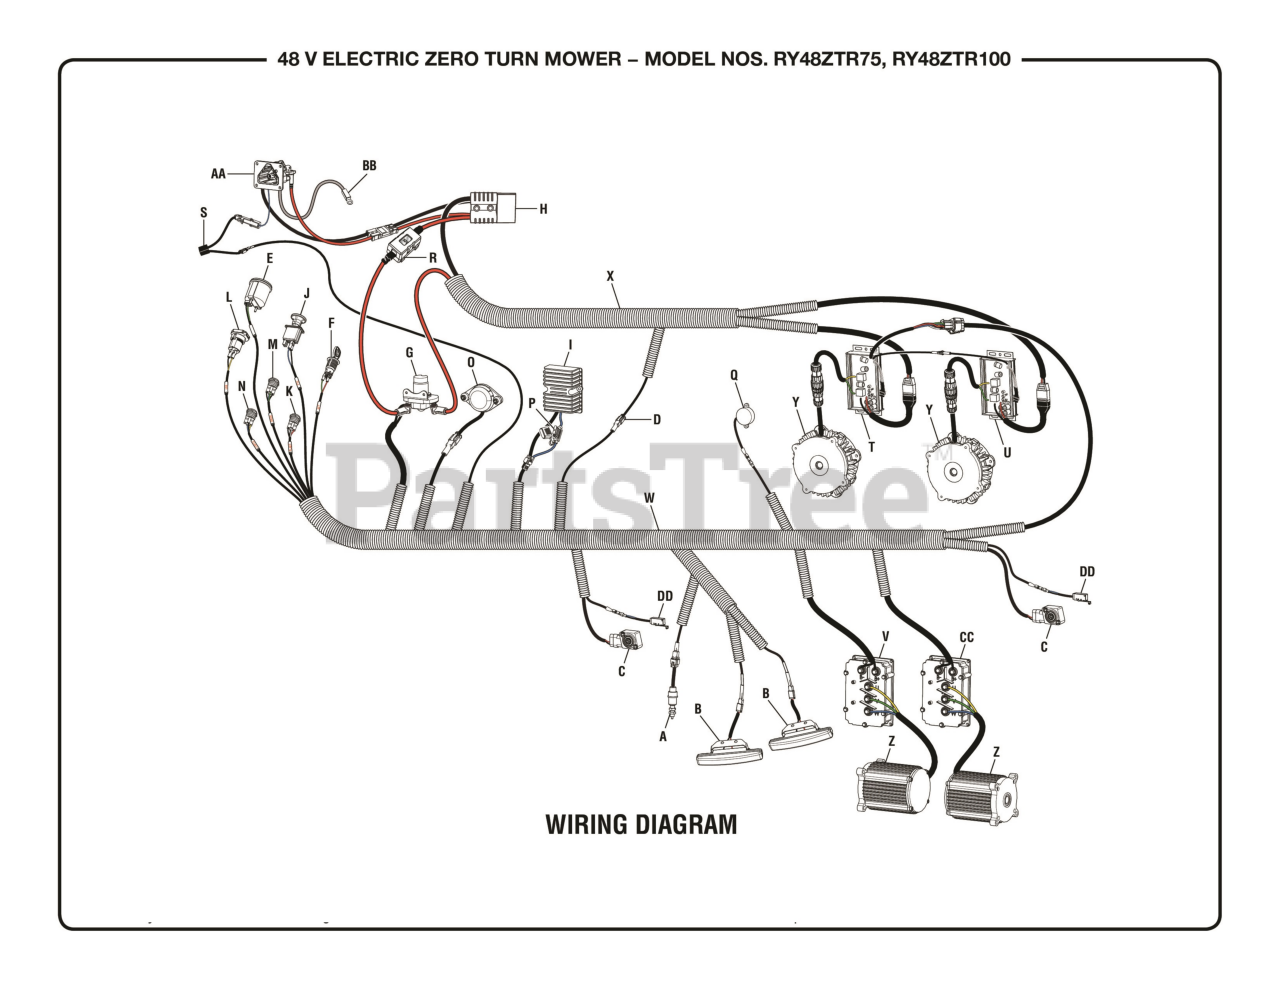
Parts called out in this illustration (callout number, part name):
A	Brake Switch
B	Headlights
C	Accelerator
D	Ground
E	Battery Gauge
F	Switch w/Key
G	Relay
H	Battery Connector
I	12 Volt Power Converter
J	Blade PTO
K	Blade Speed
L	USB
M	Drive Speed
N	Headlight Switch
O	Seat Switch
P	2 Amp Fuse
Q	Beeper
R	125 Amp Fuse
S	Charger Lockout Circuit
T	Master Deck Motor Controller
U	Slave Deck Motor Controller
V	Master Drive Motor Controller
W	Main Wiring Harness
X	Battery Output Cable
Y	Deck Motor
Z	Drive Motor
AA	Charger Port
BB	Temperature Sensor
CC	Slave Drive Motor Controller
DD	Neutral Switch
